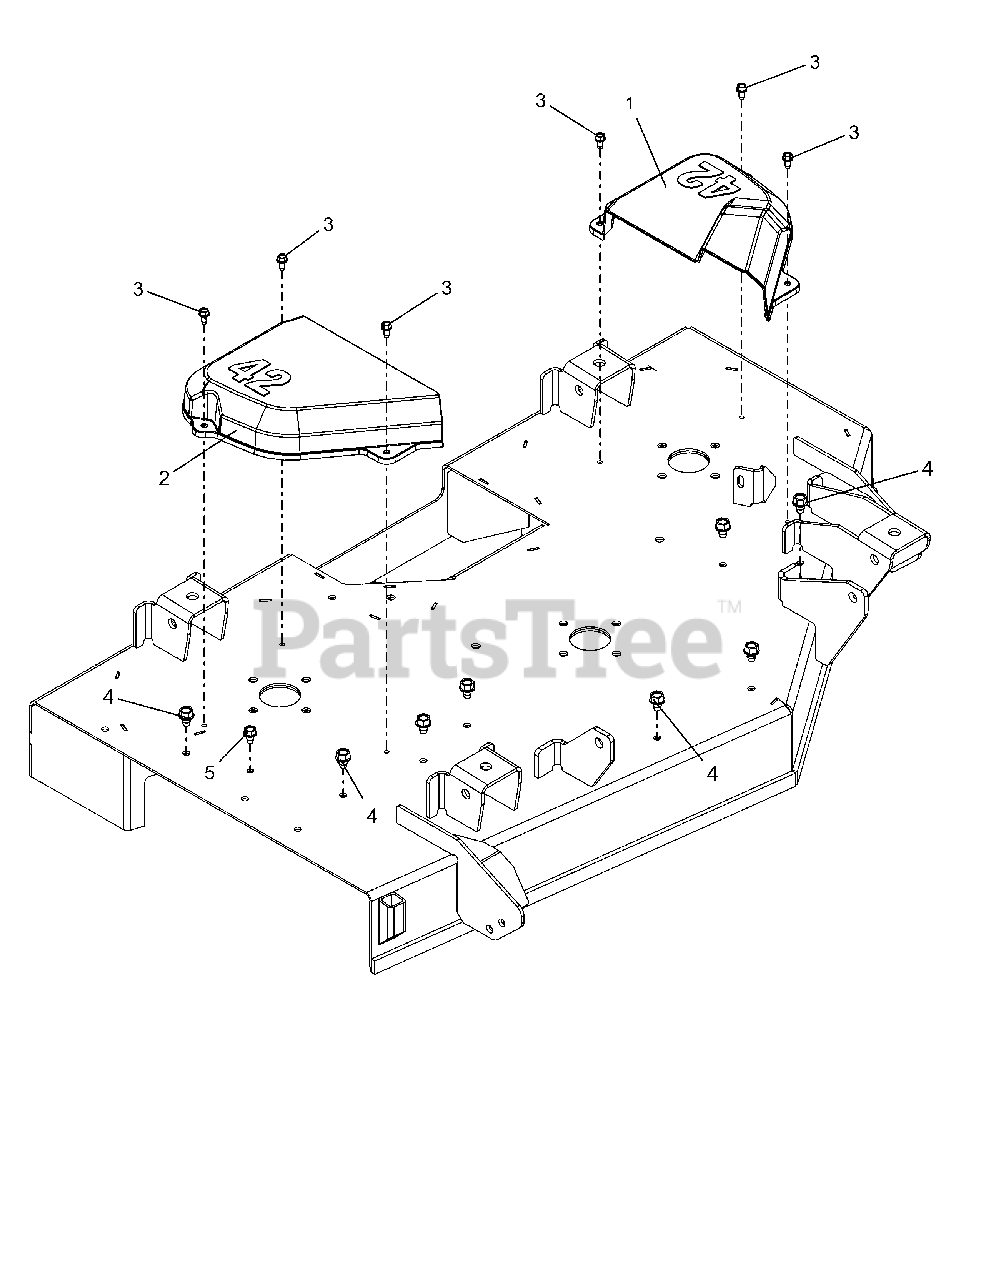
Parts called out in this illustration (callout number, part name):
1	COVER, BELT 42" LH
2	COVER, BELT 42" RH
3	SCR-TAP .25-20X.50 HWH ZCC
4	SCR,TAP .375-16X.50 HWH TR ZCC
5	@SCR-TAP .31-18X.50 HWH TR YWZ
